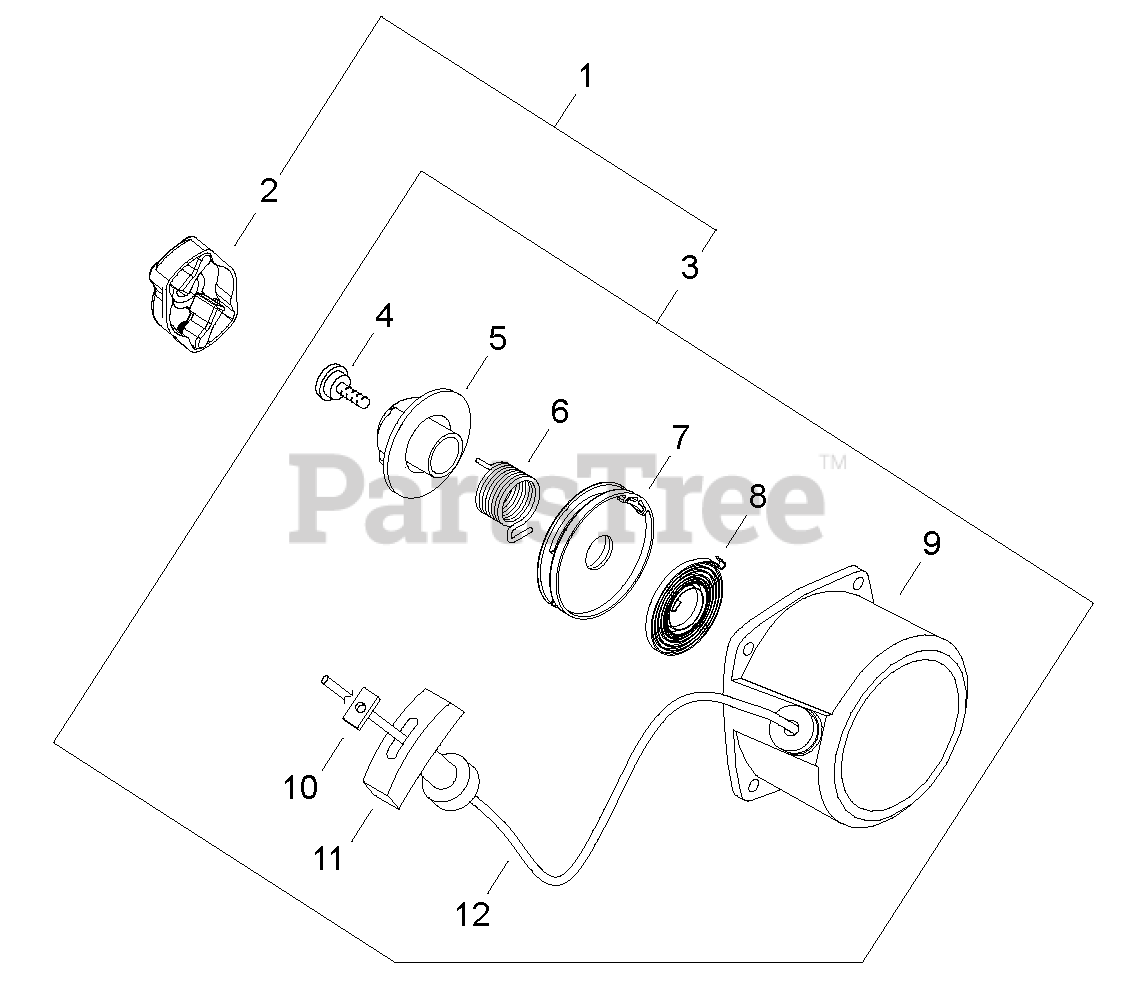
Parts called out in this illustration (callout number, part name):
1	EASY-TO-PULL RECOIL STARTER KIT
2	REEL, ROPE
3	STARTER ASSY
4	SCREW - 5
5	CAM
6	SPRING
7	REEL, ROPE
8	SPRING
9	CASE, STARTER
10	RETAINER, ROPE
11	GRIP, STARTER
12	ROPE, STARTER
